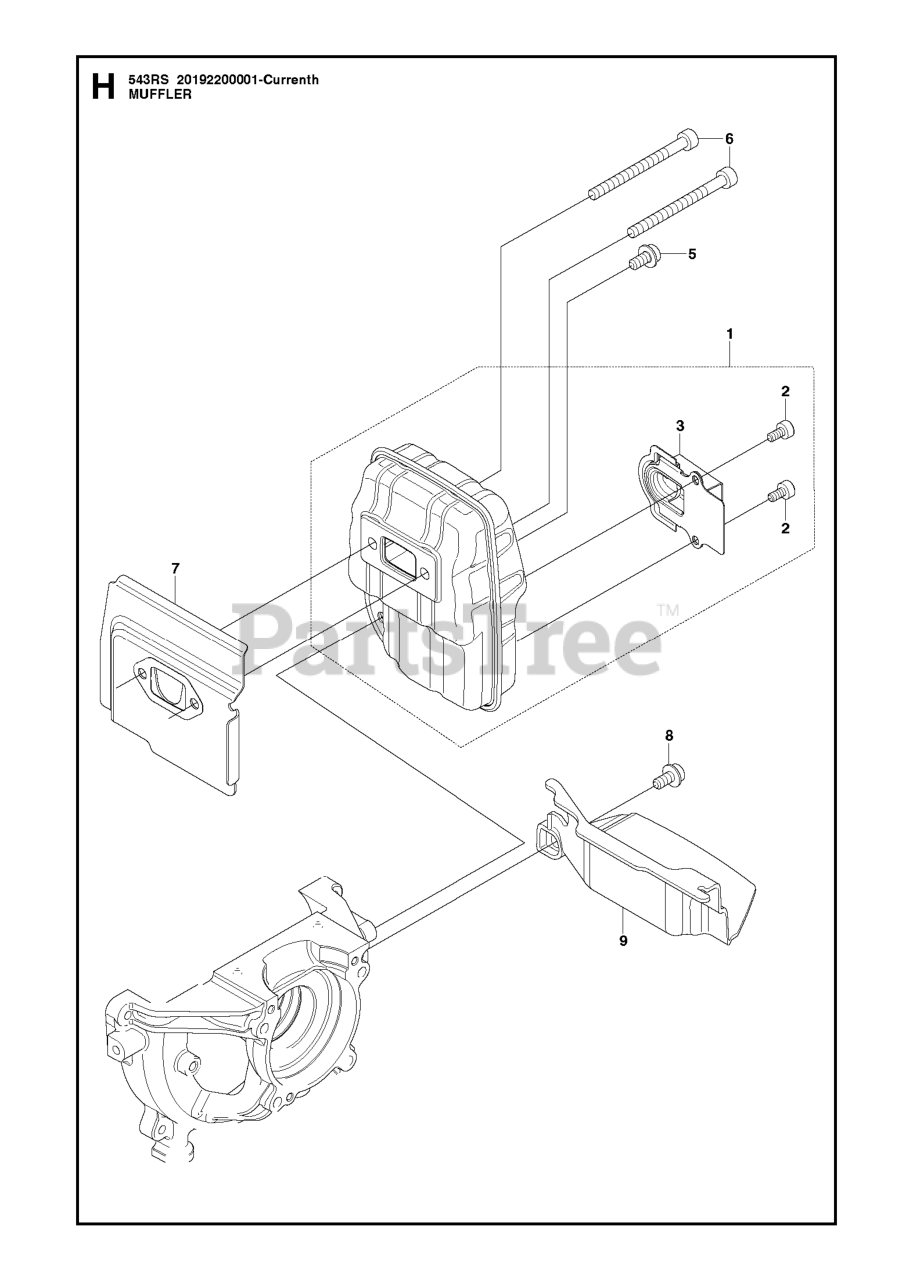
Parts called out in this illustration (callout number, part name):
1	MUFFLER ASSY
5	BOLT (RPLS T495051010-11)
6	BOLT
8	BOLT (RPLS T495051010-11)
